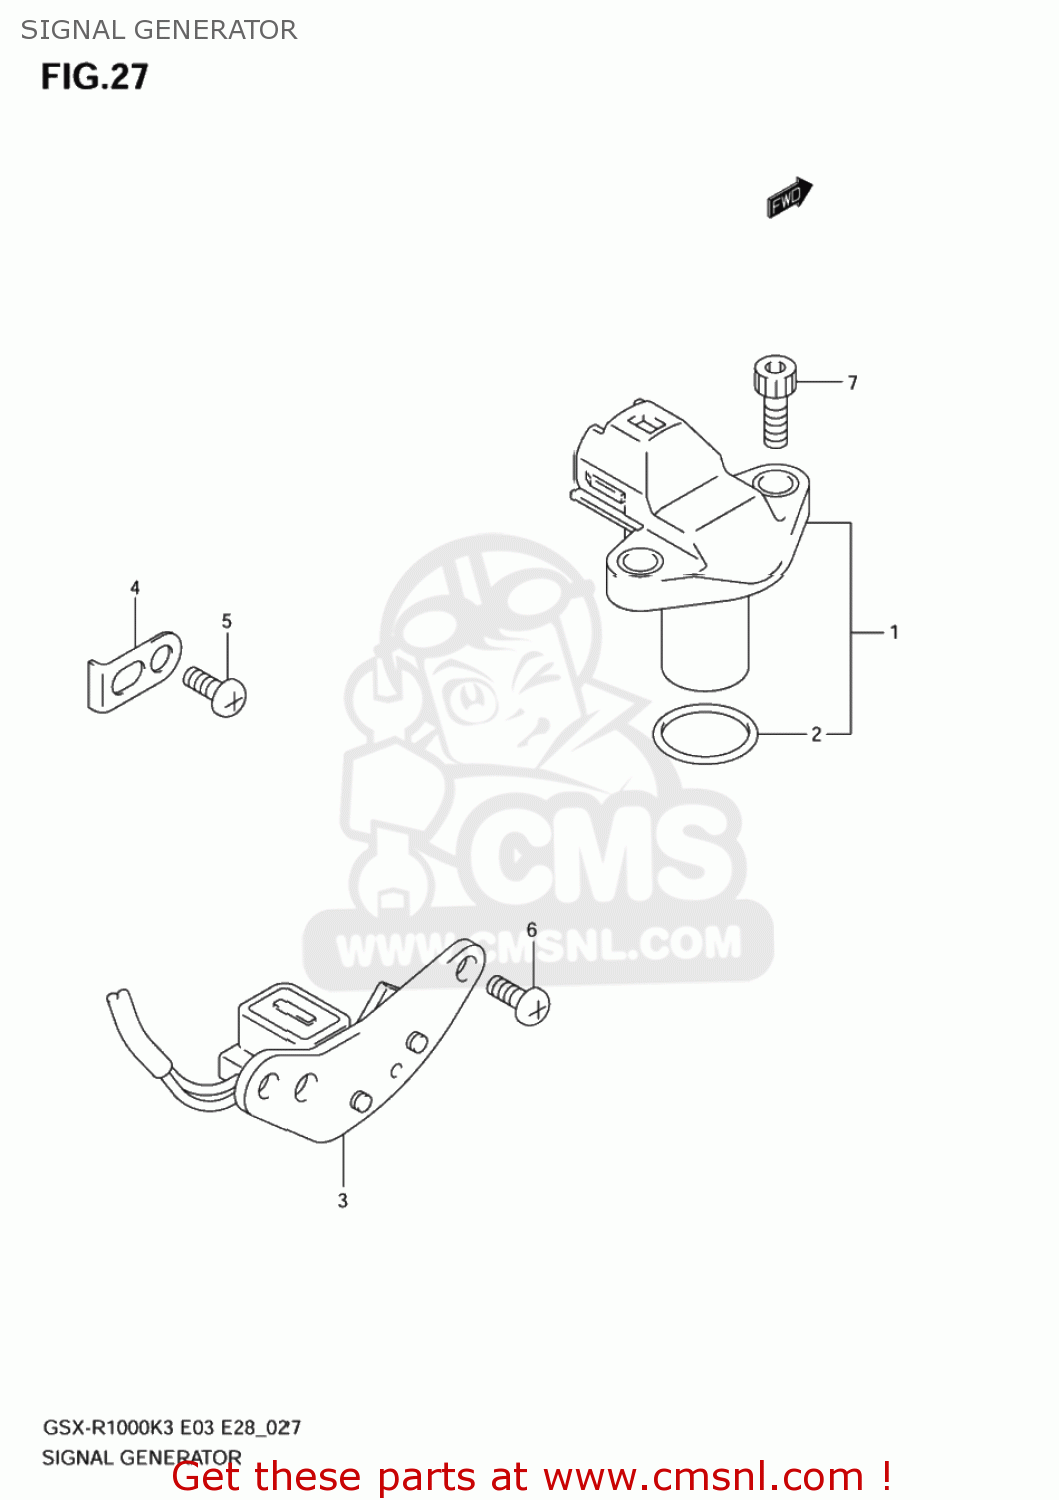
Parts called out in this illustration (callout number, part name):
1	SENSOR ASSY,CAM POSITION
2	PACKING (NAS)
3	STARTER SIGNAL GENERATOR
4	CLAMP,SIGNAL GENERATORERATOR
5	SCREW
6	SCREW
7	BOLT,OIL FILLE
